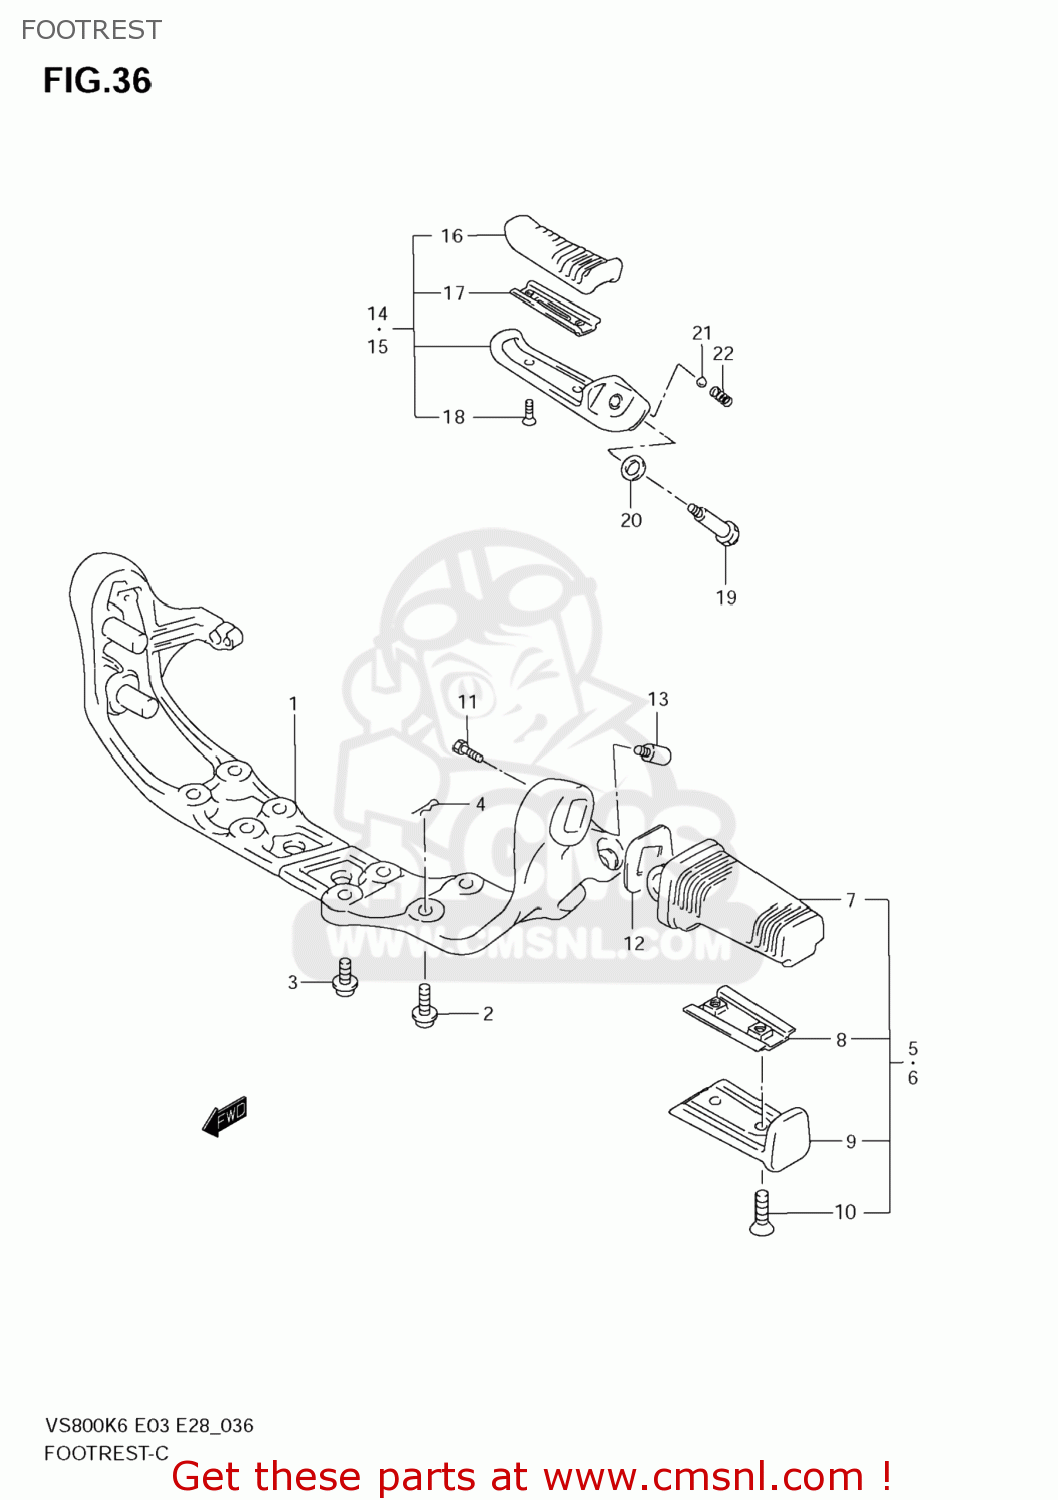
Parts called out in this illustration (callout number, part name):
1	BRACKET,FR FOOTREST
2	BOLT(8X25)
3	BOLT
4	SNAP
5	FOOTREST ASSY,FR,R
6	FOOTREST ASSY,FR,L
7	RUBBER,FR FOOTREST
8	PLATE,RUBBER STOPPER
9	COVER,FR FOOTREST
10	SCREW(5X20)
11	SCREW
12	WASHER,FR FOOTREST
13	BOLT(6X8)
14	FOOTREST ASSY,PILLION,R
15	FOOTREST ASSY,PILLION,L
16	RUBBER,PILLION FOOTREST
17	PLATE,RUBBER STOPPER
18	SCREW(5X16)
19	BOLT(6X34.5)
20	SHIM
21	BALL
22	SPRING
